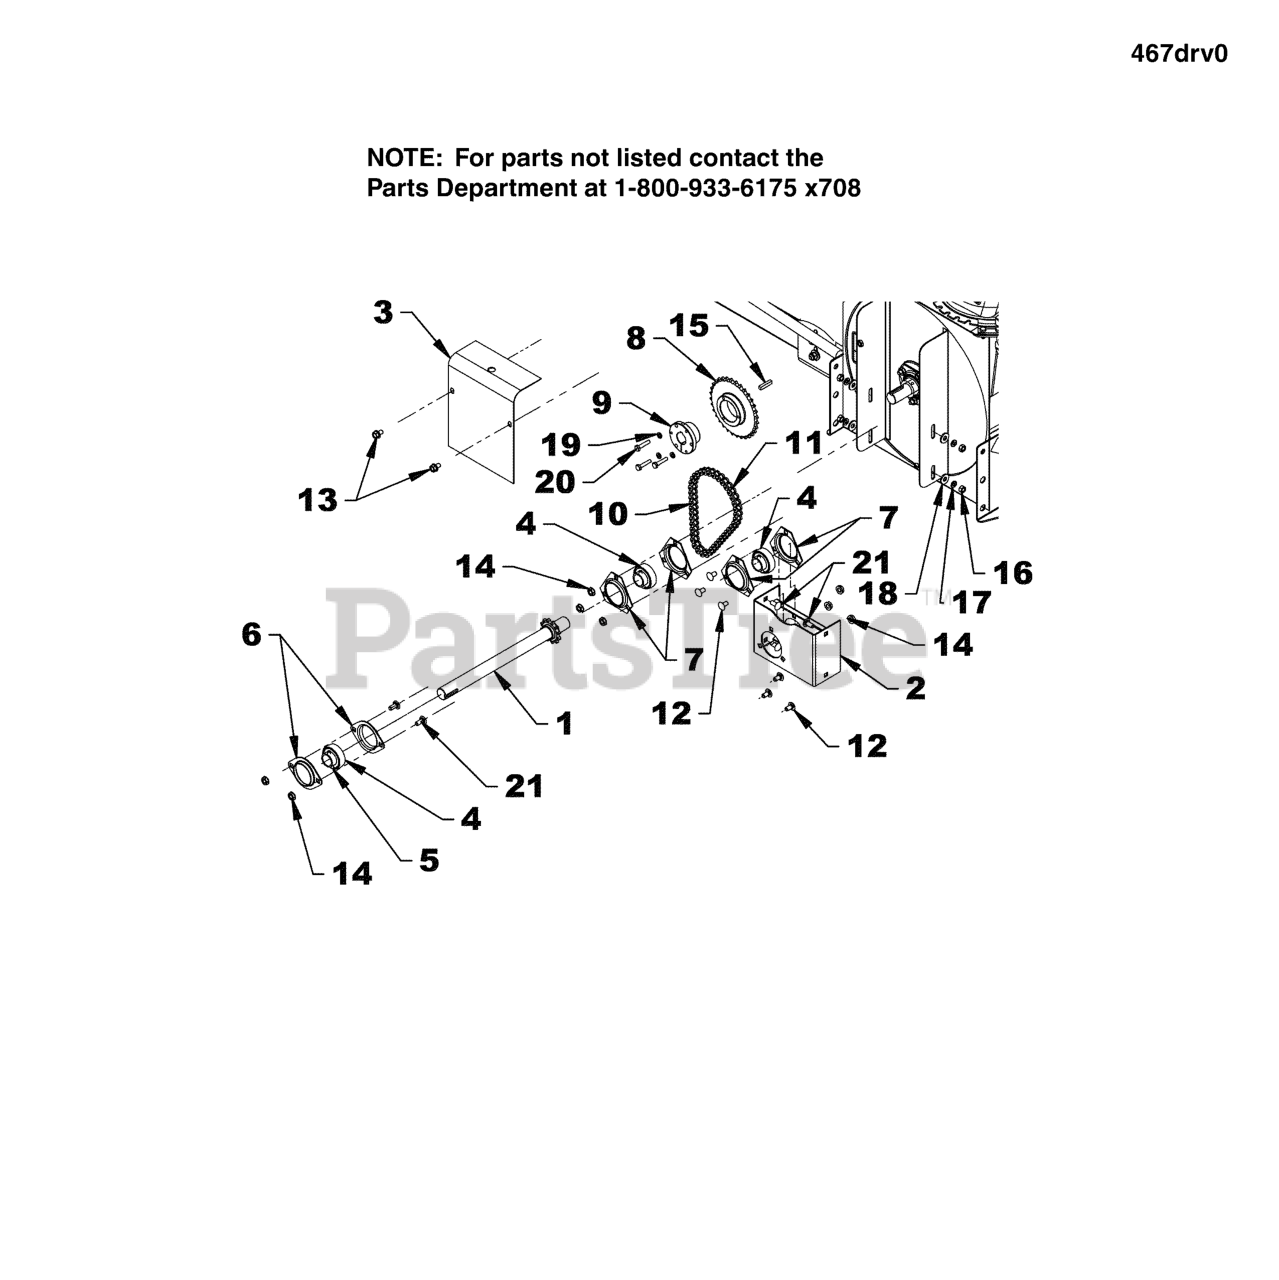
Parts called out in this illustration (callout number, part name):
1	Output shaft
2	Reduction box
3	Reduction box cover
4	Bearing Ø1" w/ setscrew
5	Allen setscrew 1/4" NC x 1/4" gr.5 black
6	Flange 2 holes for ø1" bearing , PTD
7	Triangular Flange 3 holes for Ø1" bearing PTD
8	Sprocket 40B32 tapered inside
9	Pulley Hub SH ø1" w/ bolts (to be replaced by #20) & lockwasher
10	Chain #40 x 44 links LL (w/ connecting link)
11	Connecting link #40 LL
12	Carriage bolt 5/16"NC x 5/8" gr.5 PTD
13	Serrated flange bolt 5/16"NC x 1/2" gr.2 PTD
14	Serrated flange nut 5/16"NC PTD
16	Hex. nut 5/16"NC PTD
17	Lockwasher 5/16", PTD
18	Flat washer Ø5/16" Int., PTD
20	Hex. bolt1/4" NC X 1 1/2" gr.5, PTD
21	Carriage bolt 5/16"NC x 3/4" gr.5, PTD
